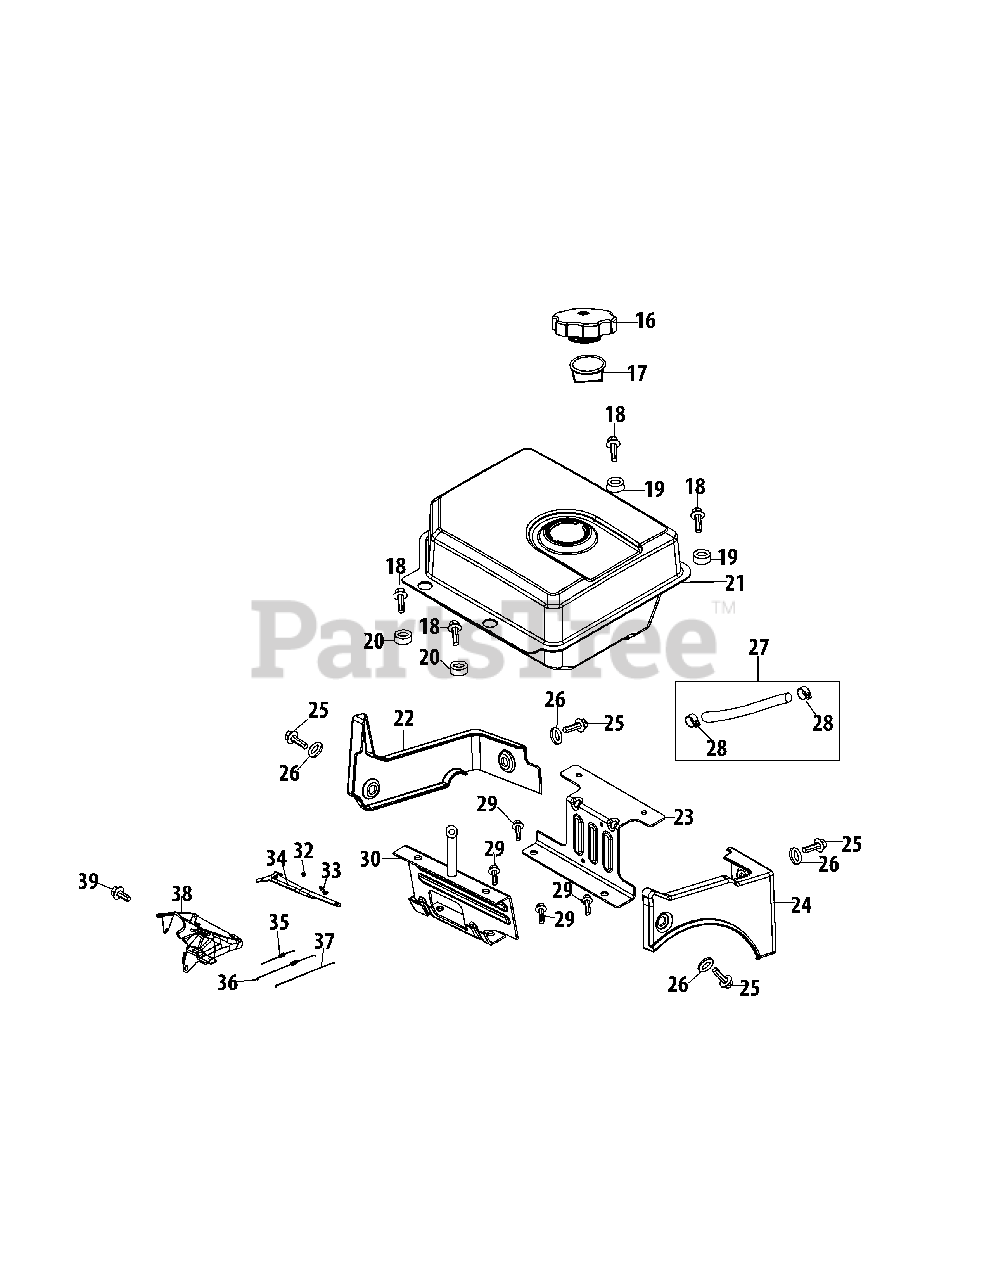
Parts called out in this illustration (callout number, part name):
16	Fuel Cap Assembly
17	Fuel Level Indicator
18	Bolt M8×20
21	Fuel Tank Assembly
22	Governor Cover
23	Rear Mainting Bracket Assy.
24	Decorate Cover
25	Bolt M6×16
27	Fuel Line Kit
28	Fuel Hose Clamp
29	Bolt M8×14
30	Gas Tank Support Bracket
32	Nut M6
33	Governor Arm Bolt
34	Governor Arm
35	Governor Spring
36	Throttle Linkage Spring
37	Throttle Linkage
38	Primer Bracket
39	Bolt, M6×12
